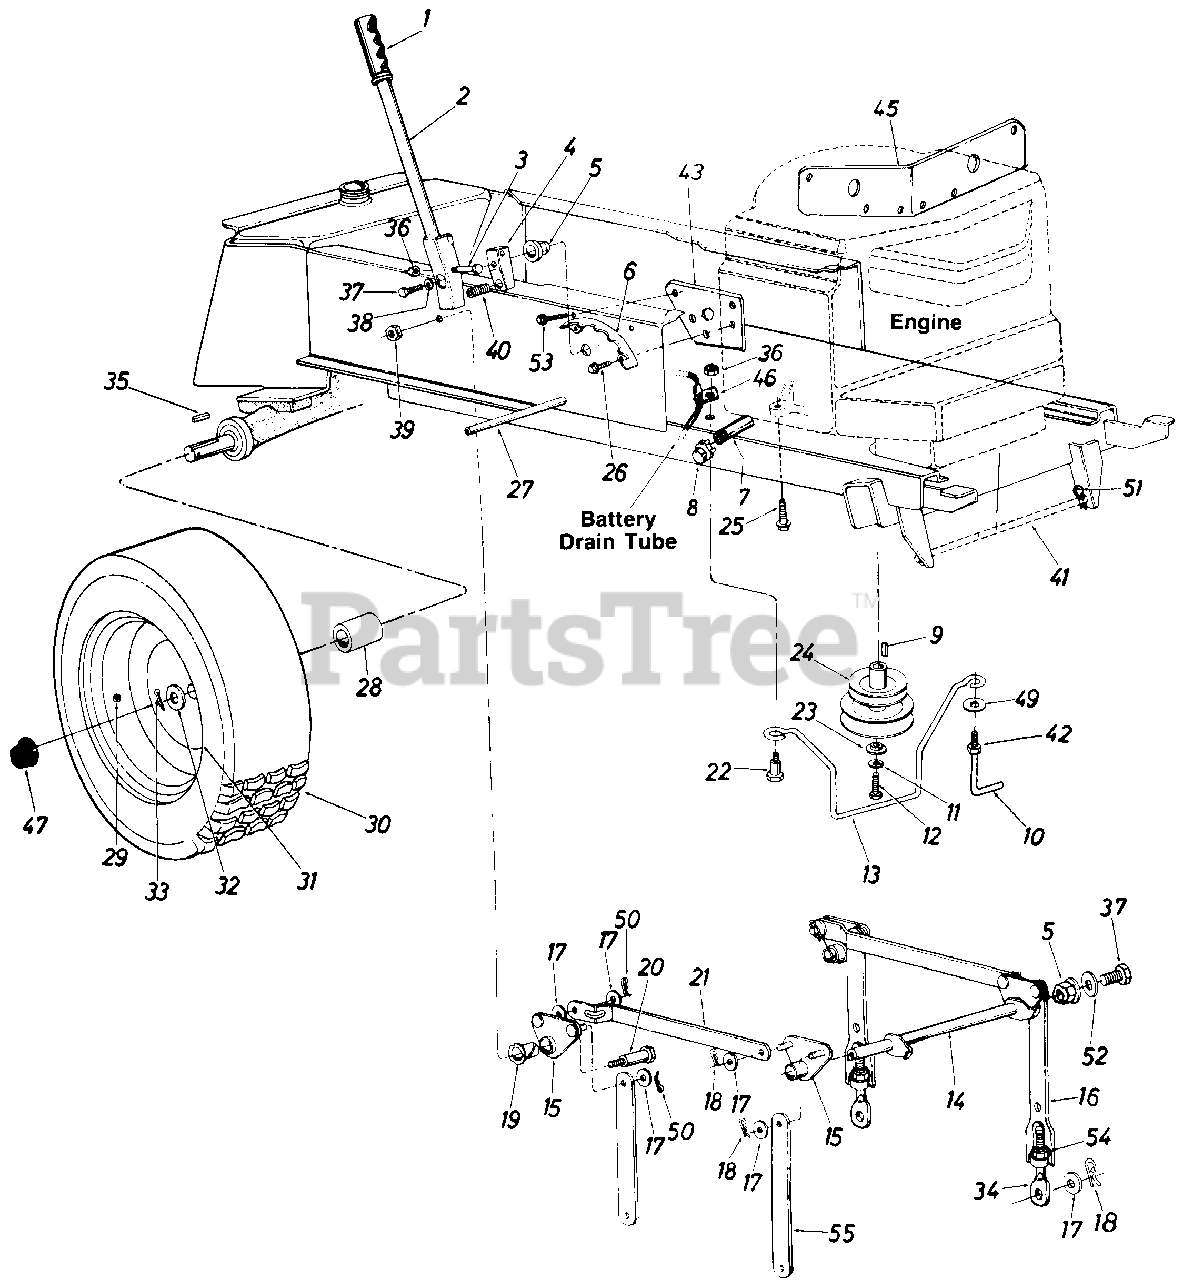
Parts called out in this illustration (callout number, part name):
2	Lift Handle Ass'y.
3	Hex Scr. 5/16-18 x 1.50" Lg.
4	Lift Shaft Drive
5	Plastic Hex Brg. 5/8" I.D.
6	Index Brkt. Deck Lift
7	Pipe Nipple 3/8-18 Npt.
8	Pipe Cap 3/8-18 Npt.
9	Sq. Key 1/4" x 1/4" x 1.50" Lg.
10	Belt Guard Lock Pin
11	L-Wash. 7/16" Scr.
12	Hex Scr. 7/16-20 x 1.50" Lg.
13	Belt Guard
14	Lift Shaft Ass'y.
15	Lift Pivot Brkt. Ass'y.
16	Adj. Deck Lift Link
17	Fl-Wash. 1/2" I.D. x 1.00" O.D. x .090
18	Hairpin Cotter
19	Nyliner 5/8" I.D. x .88" Lg.
20	Shld. Scr. 5/8" Dia. x .96" Lg. 3/8-16
21	Connecting Link
22	Shld. Scr. .437 Dia. x .268 0 Lg. 5/16-18
23	Flat Wash. .44" I.D. x 1.25" O.D. x .17
24	Two-Step Engine Pulley 4.75" & 5.56
25	Hex Wash. Hd. Scr. 3/8-16 x 1.25" Lg.
26	Hex Thd. Rolling Scr. 5/16-24 x .50" Lg .
27	Running Board Rod
28	Spacer 1.0" I.D. x 1.25" O.D. x 2.12" Lg.
29	Air Valve
30	Rear Wheel Ass'y. Comp.
33	Cotter Pin 3/16" Dia. x 1.50" Lg.
34	Eye Bolt Adj. Link 1/2-13 Thd.
35	Sq. Key 1/4 x 3.0"
36	Hex Cent. L-Nut 5/16-18 Thd.
37	Hex Scr. 5/16-24 x .62" Lg.*
38	L-Wash. 5/16" Scr.
39	Hex Top L-Nut 3/8-16 Thd.
40	Compression Spring
41	Deck Connecting Rod
42	Hex Nut 5/16-24 Thd.
43	Index Brkt. Reinforcement Plate
45	Heat Sheild
46	Mounting Clamp
47	Hub Cap
49	Belle-Wash. .39" I.D.
50	Cotter Pin .09 Dia. x 1.0" Lg.
51	Int. Cotter Pin
52	Flat Wash. .34" I.D. x 1.12" O.D. x .125
53	Hex Wash. Hd. AB-Tap Scr. 5/16 x .62" Lg.
54	Hex Nut '/2-13 Thd.
55	Deck Link
